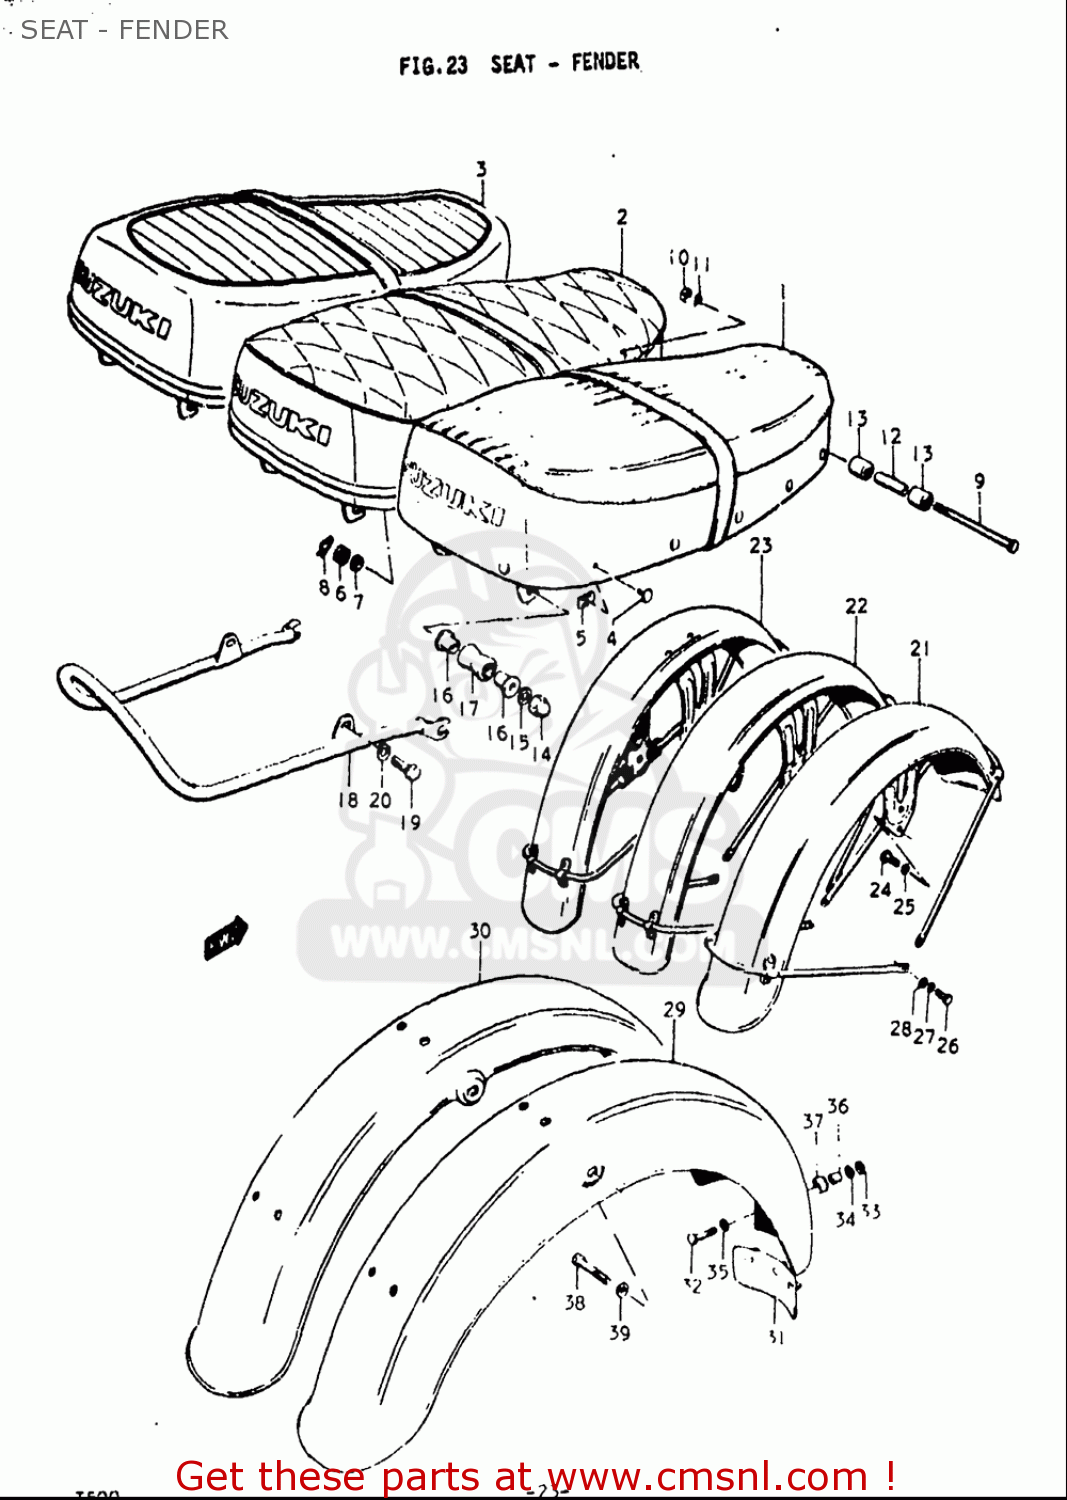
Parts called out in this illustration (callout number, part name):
6	NUT
7	WASHER
9	BOLT 8X125
10	NUT
11	WASHER,LOCK
14	NUT
15	WASHER,LOCK
17	BUSH
19	BOLT
20	WASHER,LOCK
24	BOLT
25	WASHER,LOCK
26	BOLT
27	WASHER,LOCK
28	WASHER
31	GUIDE,RR FENDER MUD
32	BOLT
33	NUT
34	WASHER,LOCK
35	WASHER(6.5X24X1.6)
36	SPACER(6.5X10X7)
37	CUSHION
38	BOLT(8X47)
39	WASHER
